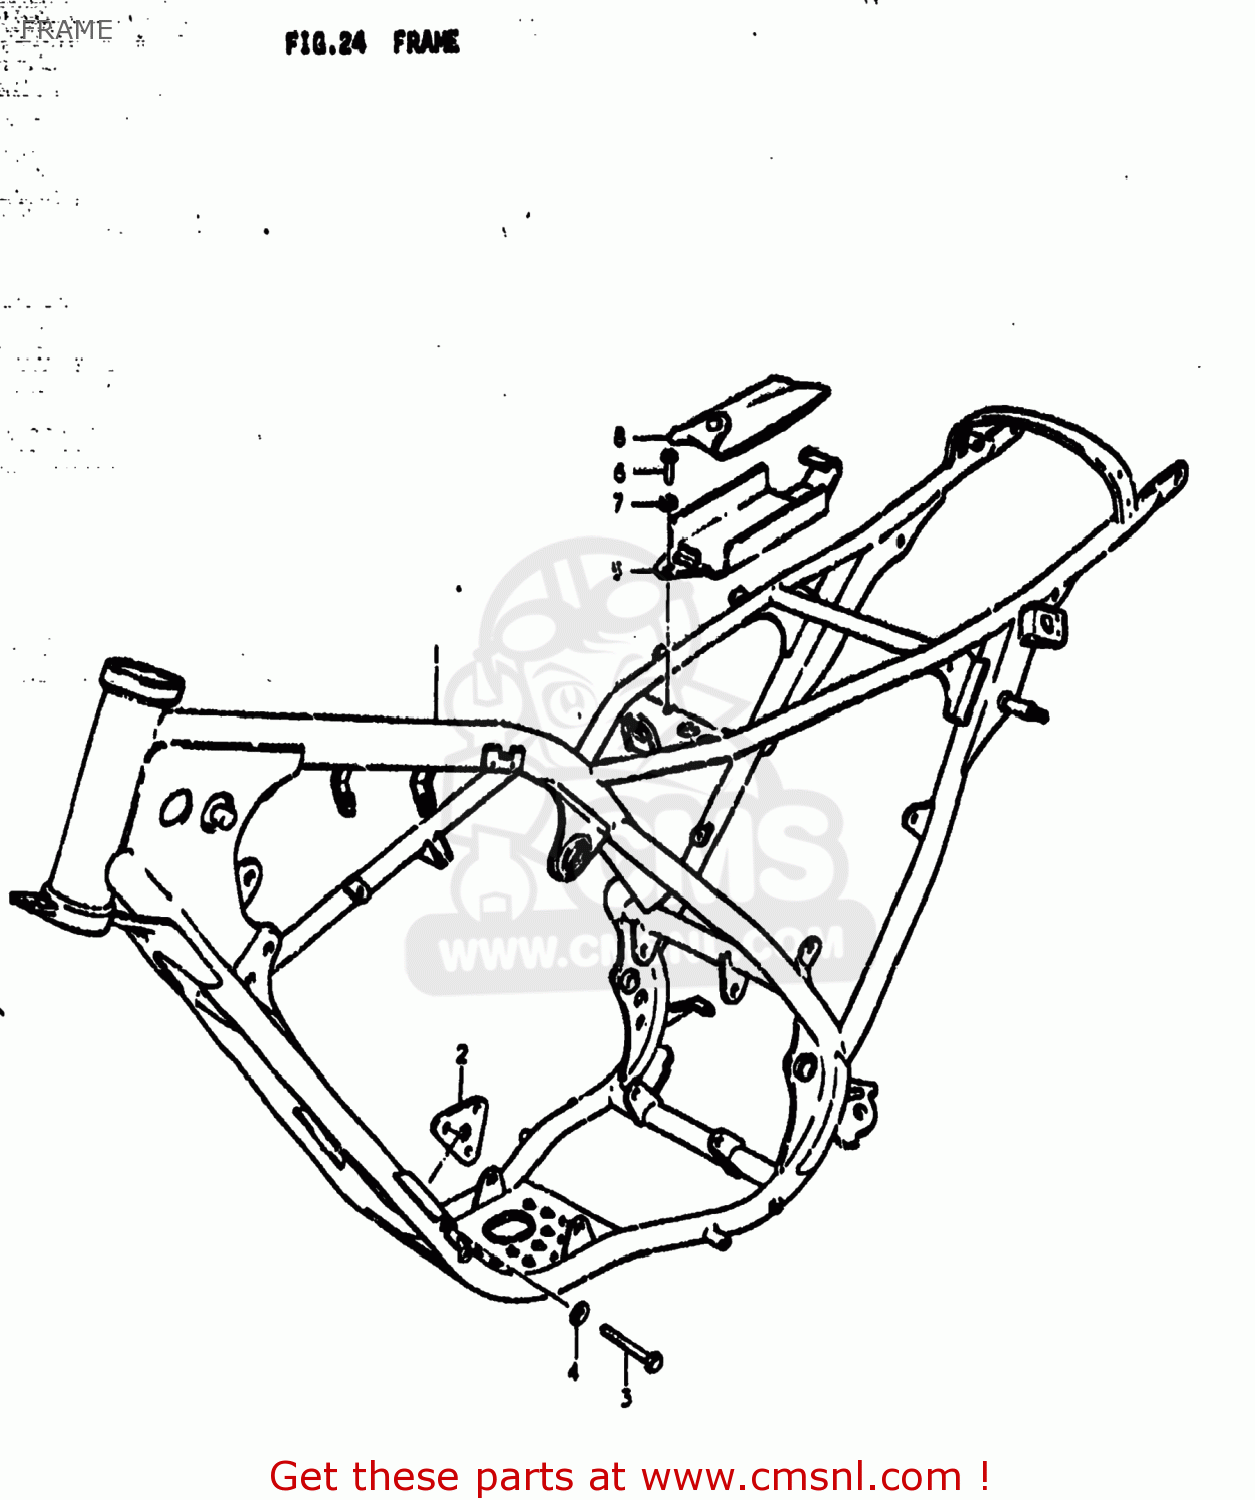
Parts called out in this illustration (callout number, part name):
1	FRAME
2	PLATE,ENG MTG,L
3	BOLT 8X55
4	WASHER
5	HOLDER,TOOL
6	SCREW
7	WASHER
8	TOOL ASSY
